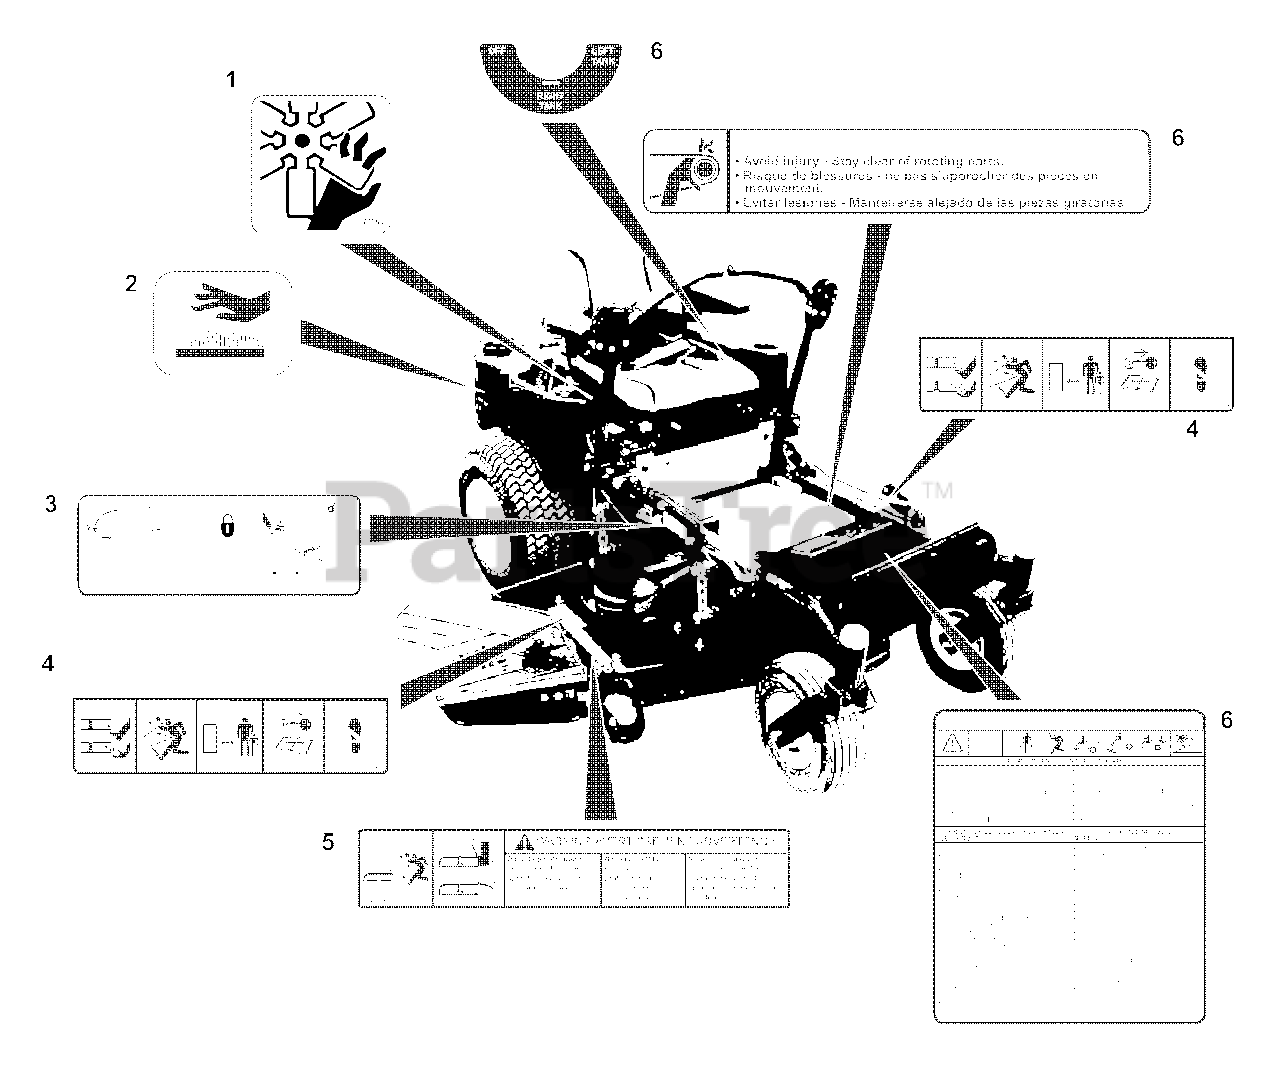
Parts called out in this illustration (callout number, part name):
1	Decal, Danger Fan
2	Decal, Hot Surface
3	Decal, Deck Service
4	Decal, Mower Pan Head Danger
5	Decal, Warning
6	Set, Decal Common Danger/Fuel
